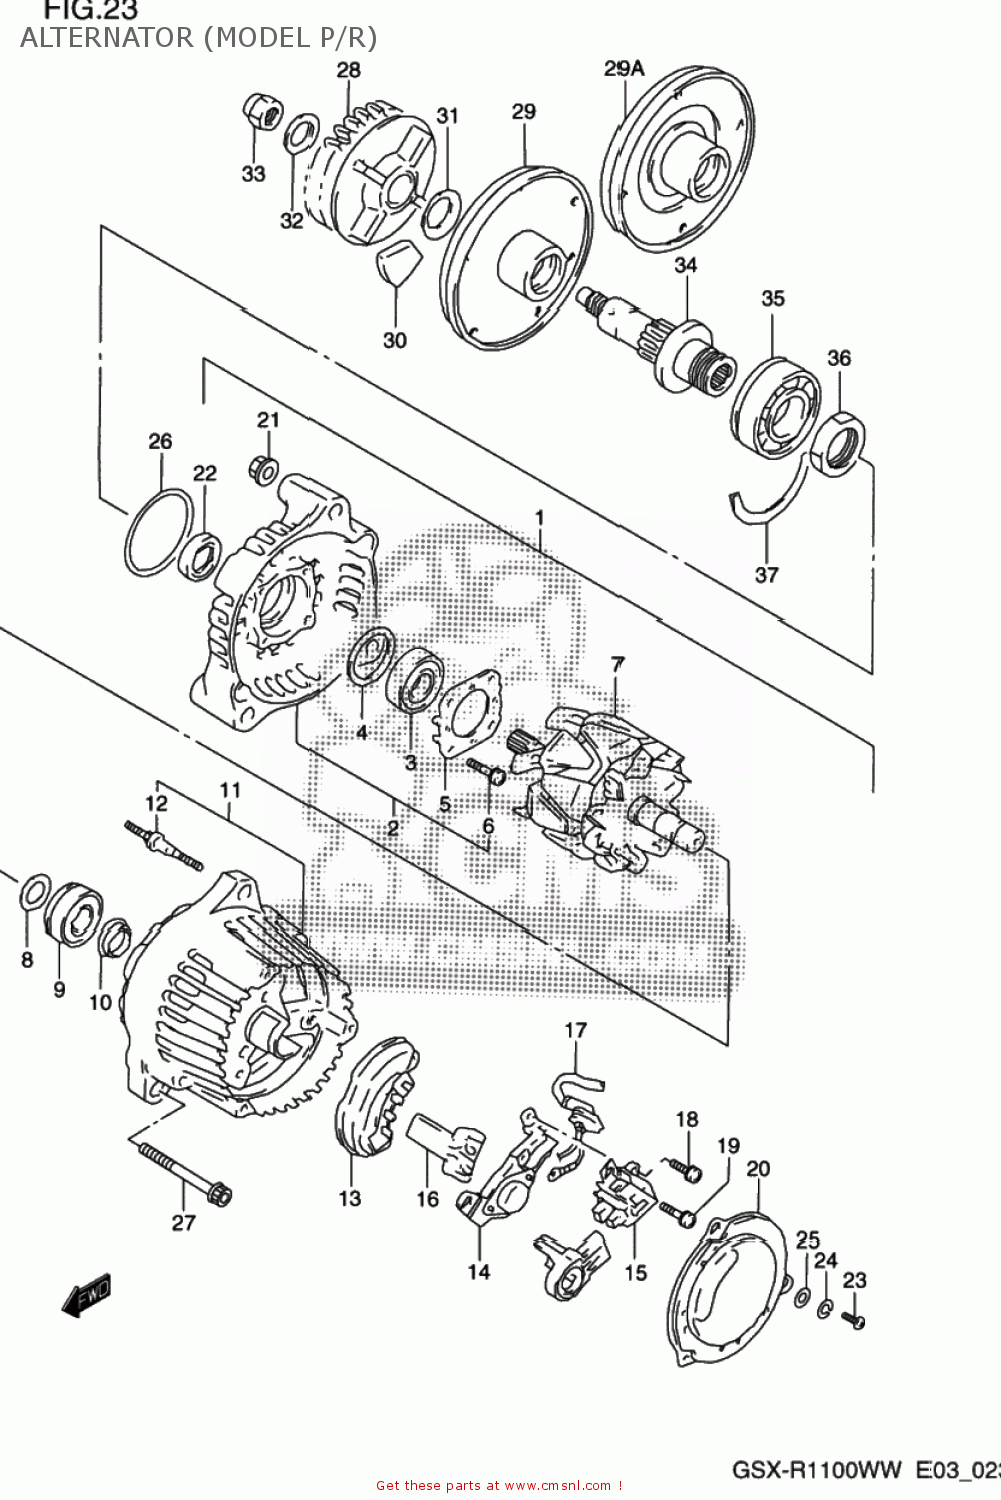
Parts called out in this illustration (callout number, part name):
1	ALTERNATOR ASSEMBLY
2	FRAME,DRIVE END
3	BEARING
4	COVER,BEARING
5	RETAINER,BEARING
6	SCREW,BEARING RETAINER
7	ROTOR ASSEMBLY
8	COVER,BEARING
9	BEARING
10	COVER(2)
11	FRAME,END
12	STUD BOLT
13	HOLDER,RECTIFIER
14	REGULATOR
15	HOLDER,BRUSH
16	COVER,RECTIFIER
17	WIRE,LEAD
18	SCREW
19	SCREW
20	COVER
21	NUT
22	SEAL SET,OIL
23	SCREW
24	WASHER,LOCK
25	WASHER,5MM
26	O RING
27	BOLT
28	GEAR,GENERATOR DRIVEN
29	HOUSING,GENERATOR DAMPER
29A	HOUSING,GENERATOR DAMPER
30	DAMPER,GENERATOR
31	WASHER
32	WASHER
33	NUT
34	SHAFT,GENERATOR DRIVE
35	BEARING(25X52X15)
36	NUT
37	C RING
